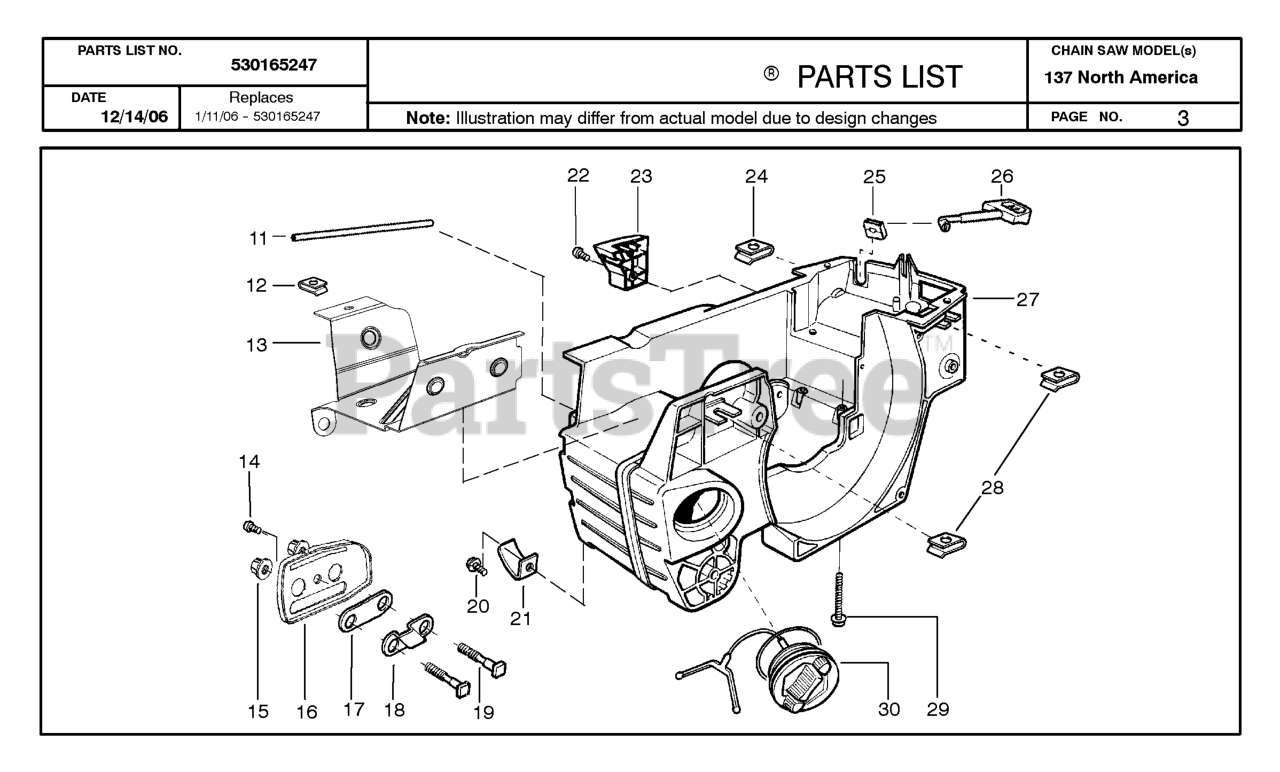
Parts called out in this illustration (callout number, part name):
13	HEATSHIELD, LOWER
17	OIL TANK GASKET
18	PLATE,BAR MOUNT
19	BAR BOLT 36/41
21	CHAIN CATCHER 36/41
23	LIMITER COVER
25	CHOKE GUIDE 36/41
26	CHOKE 36/41
27	KIT ASSY CHASSIS
29	SCREW M5-0.8X35M TAP
